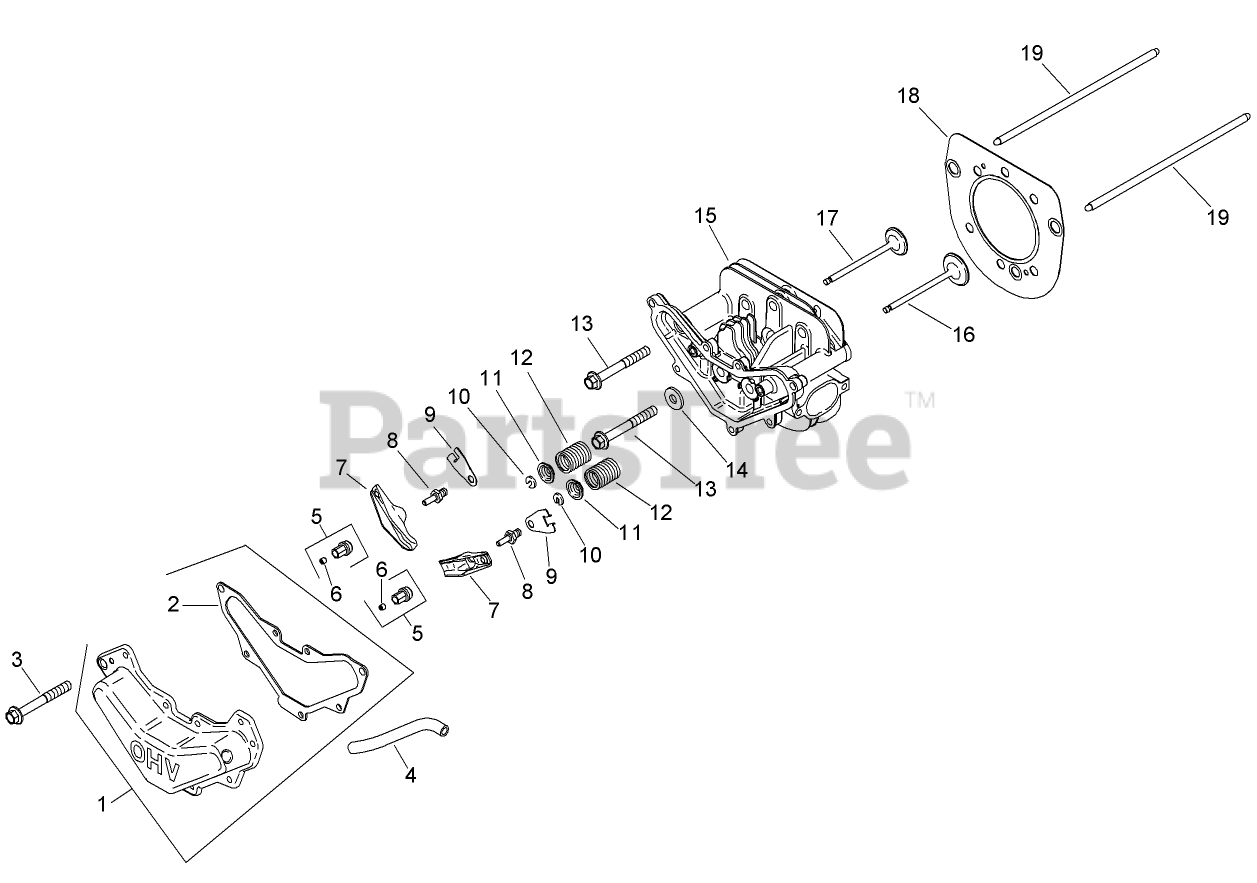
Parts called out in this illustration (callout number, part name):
1	Valve Cover Kit (Includes 2)
2	Gasket-cover, valve
3	SCREW-HHFTF (M6X1.0X20)
4	HOSE-BREATHER
5	Pivot-Arm, Rocker (Includes 6)
6	Screw-Set
7	Arm-Rocker
8	Stud-Rocker
9	Plate-Guide, Push Rod
10	Lock-Retainer
11	Cap-Spring, Valve
12	Spring-Valve
13	Screw-Flange, Hex (M10x1.5x37)
14	Washer-Flat (1/2)
15	CYLINDER HEAD ASM
16	Valve-Exhaust
17	Valve-Intake
18	Cylinder Head Gasket Kit (Includes 2, 13-14)
19	Rod-Push
